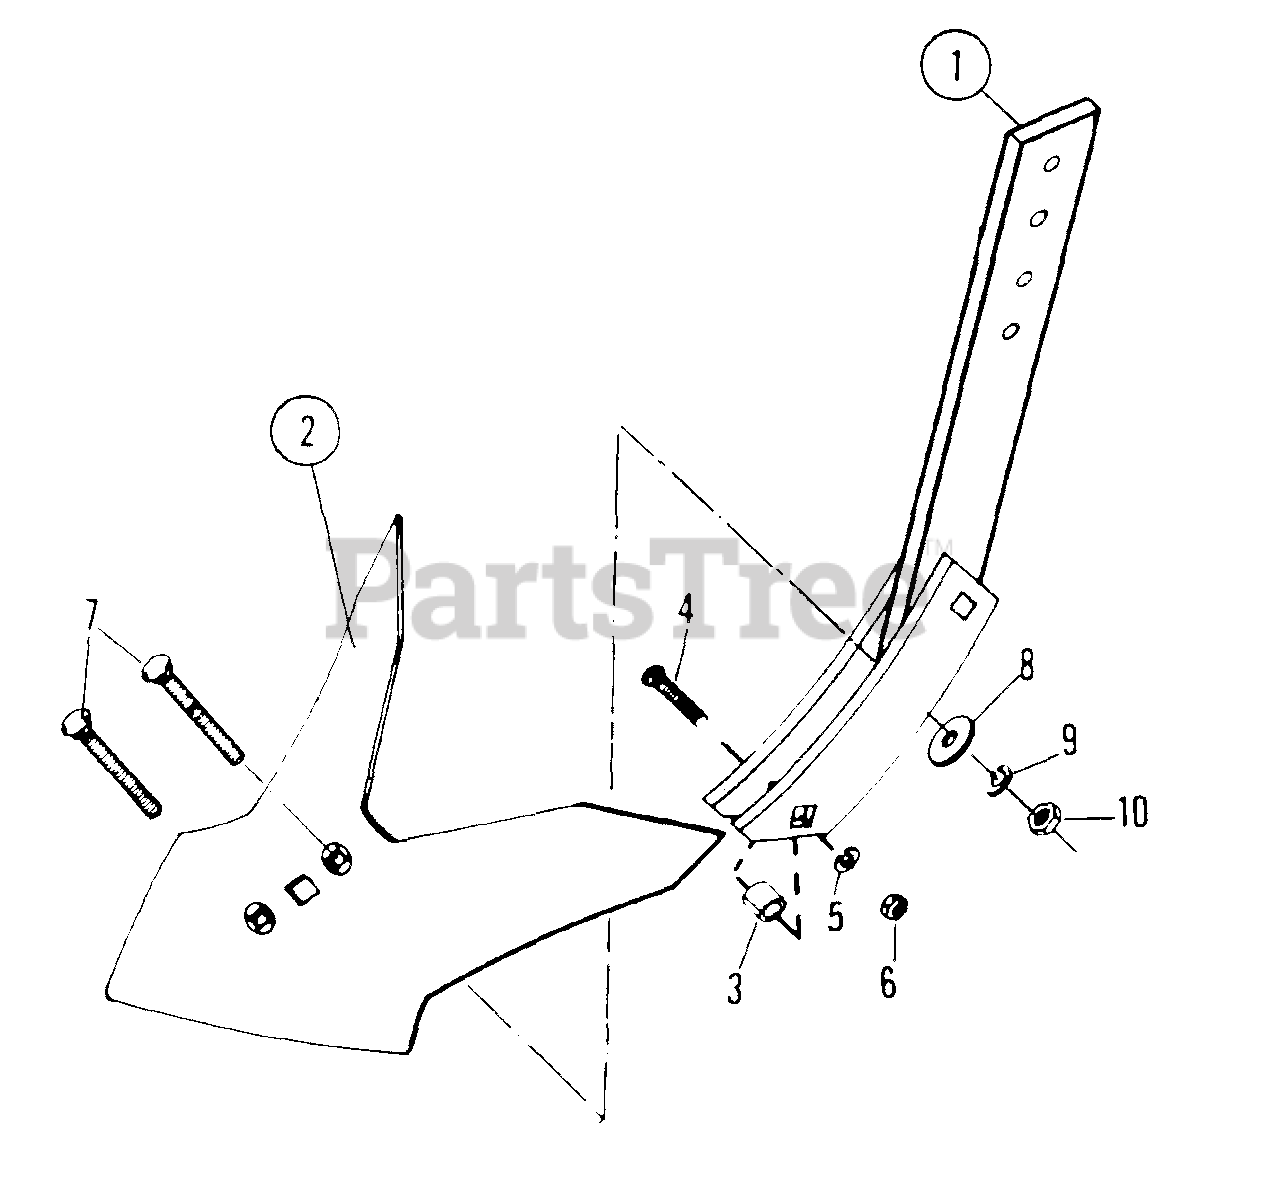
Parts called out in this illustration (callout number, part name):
1	STANDARD, MIDDLE BUSTER
2	PLOW, MIDDLE BUSTER
3	BUSHING
4	BOLT, 3/8 x 1-1/2 CARRIAGE
5	LOCKWASHER, 3/8"
6	NUT, 3/8 HEX
7	BOLT, 7/16 x 3 PLOW
8	WASHER, 7/16 SPECIAL
9	LOCKWASHER, 7/16"
10	NUT, 7/16 HEX
